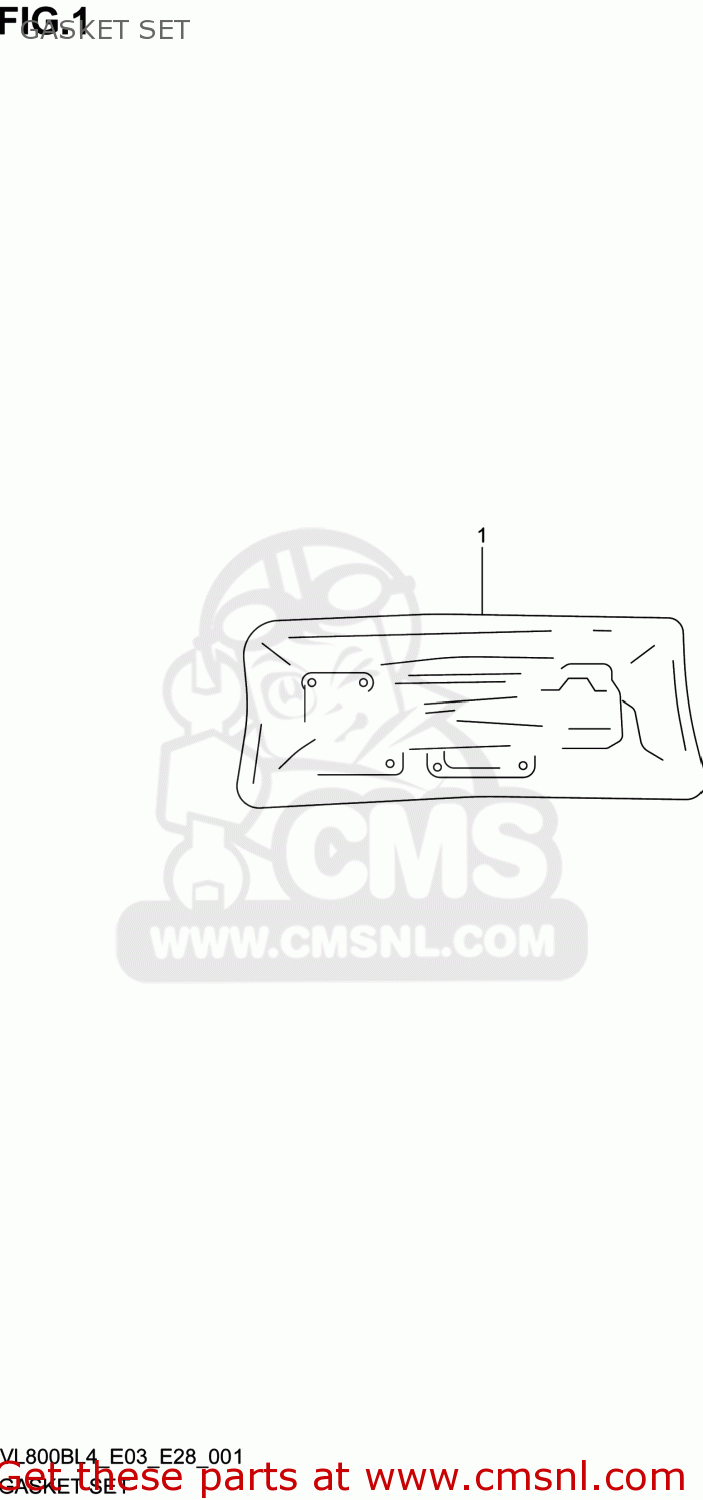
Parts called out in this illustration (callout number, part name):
1	GASKET SET (NAS)
2	GASKET,CYLINDER HEAD WATER (NAS)
3	GASKET,CYLINDER HEAD FR (NAS)
4	GASKET,CYLINDER HEAD RR (NAS)
5	GASKET,INSPECTION CAP (NAS)
6	GASKET,BREATHER COVER (NAS)
7	GASKET,CYLINDER (NAS)
8	GASKET,CLUTCH COVER (NAS)
9	GASKET,GENERATOR COVER (NAS)
10	GASKET,EXHAUST PIPE (NAS)
11	O RING,OIL STRAINER CAP
